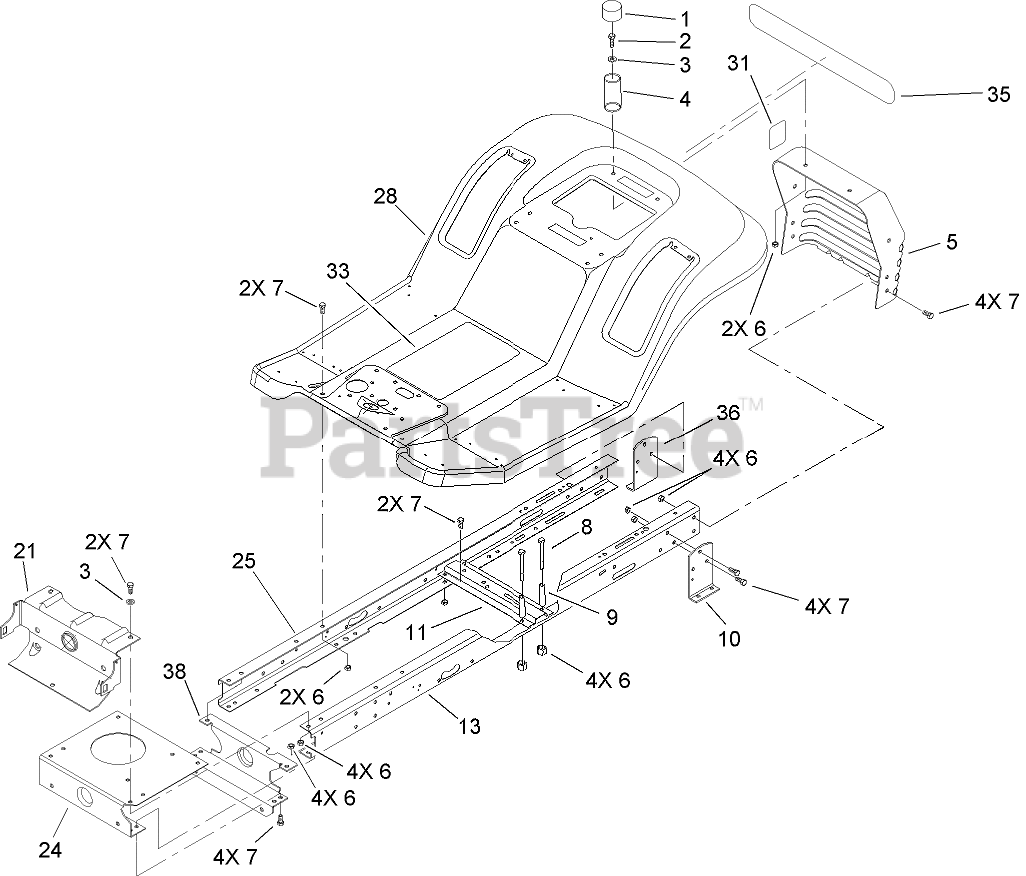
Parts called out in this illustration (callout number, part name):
1	CAP-PROTECTOR
2	SCREW-HH
3	WASHER-PLAIN
4	SPRING-COMPRESSION
5	SUPPORT-SEAT/REAR HITCH
6	NUT-LOCK, NI
7	SCREW-HH
8	SCREW-HH
9	SPACER
10	BRACKET-MOUNTING, LH
11	BRACKET-IDLER PIVOT
13	RAIL-FRAME, LH
21	SUPPORT-AXLE, FRONT
24	PLATE-MOUNTING, ENGINE
25	RAIL-FRAME, RH
28	REAR BODY ASM
31	DECAL-VALVE, DUMP
33	DECAL-INSTRUCTION, HYDRO
35	DECAL-REAR FENDER, LAWN TRACTORS
36	BRACKET-MOUNTING, RH
38	SUPPORT-REAR
